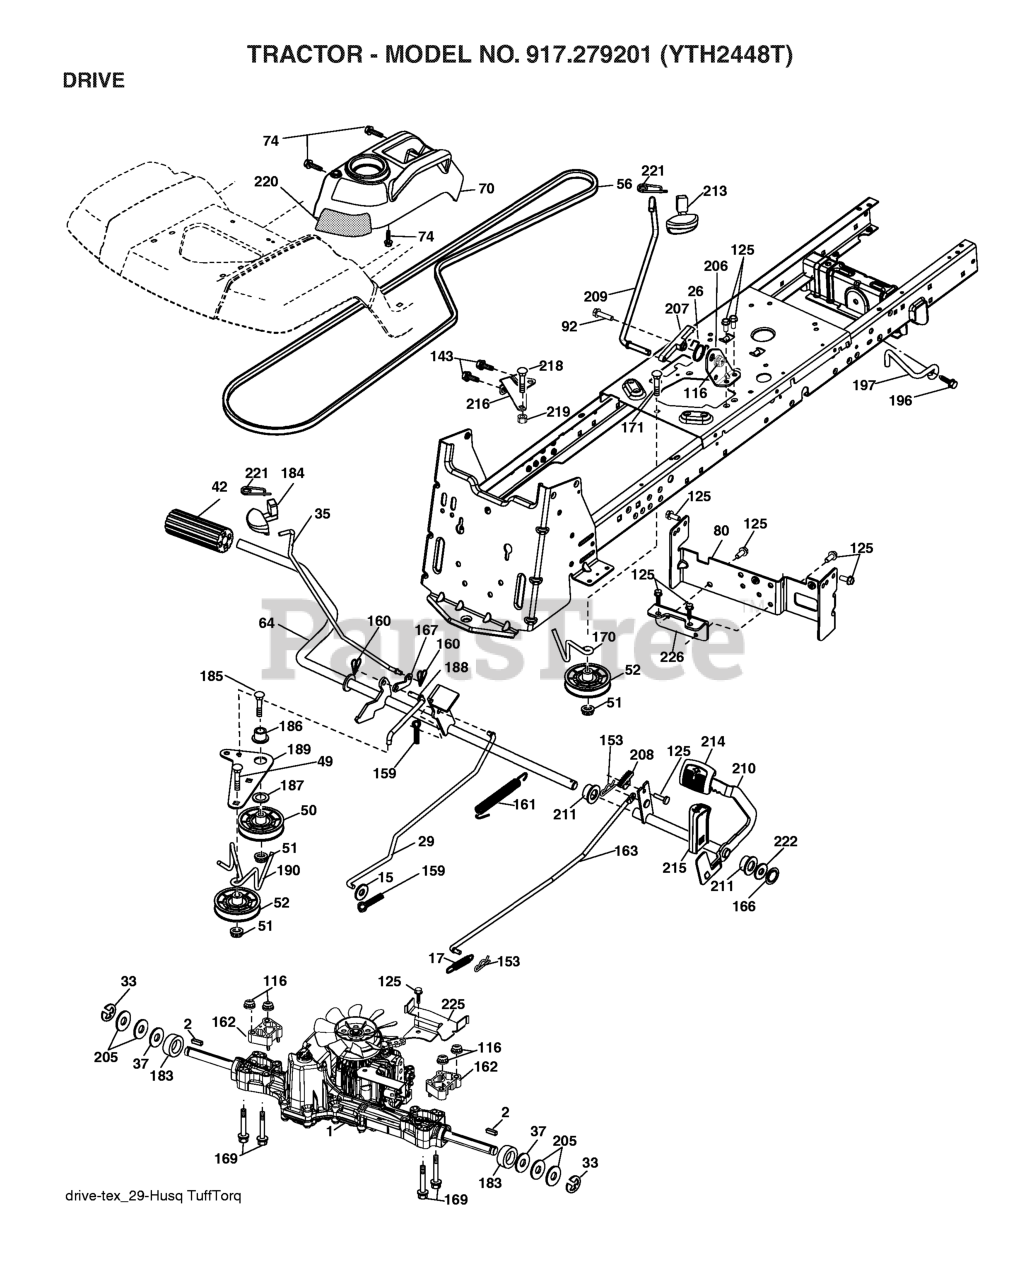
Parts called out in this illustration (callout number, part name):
1	TRANSAXLE.K46BN.PEDAL CONTROL
2	SQUARE KEY
15	WASHER
17	SPRING.BRAKE.K46
26	SPRING.RETURN.CRUISE
29	ROD.BRAKE.K46
35	ROD.BRAKE.PARKING.GT.H
42	PEDAL COVER T
50	IDLER.FLAT.910.OFFSET
51	NUT LOCK FLG 3/8-16 UNC
52	IDLER.V-GROOVE.910.OFFSET
56	V-BELT.MOWER.92.40.42/K46
64	SHAFT.ASM.PEDAL.BRK.CNTR
70	RP CONSOLE.ASM.PCH.W/TB
74	SCREW.HI-LO.CONSOLE
80	STRAP.TORQUE.HG3000/K46
92	BOLT
116	NUT LOCK HEX FLANGE 5/16-18
125	SCREW
143	Screw 5/16-18 x 1/2 Hex, Self Tapping 5/16-18 x 1/2
153	RETAINER M
159	COTTER PIN
160	RETAINER CLIP
161	SPRING.RETURN.CLUTCH.2006
162	SPACER.TRANSAXLE.18&22
163	ROD.CONTROL.PEDAL.K46
166	NUT.PUSH.625.2006
167	LATCH.BRAKE.SPRING
169	BOLT.HEX.FLNG.5/16-18X3.75
170	KEEPER.V-IDLER.CENTER.
183	SPACER AXLE
184	HANDLE.PARKG.BRK.HUSQ X667
186	SPACER.RETAINER
187	WASHER 12/32X2X10GA
188	RP.LINK.CLUTCH.GROUND.DRIVE
189	BELLCRANK.GROUND.DRIVE.TEX.
190	KEEPER.BELLCRANK.DRIVE
196	SCREW 3/8-16X1
197	LINK.CLUTCH.ANIT-ROTAT
206	BRKT.MOUNT.LATCH.CRUIS
207	LATCH.CONTROL.CRUISE
208	GEAR.SECTOR.CONTROL.CR
209	ROD.CONTROL.CRUISE.GT.
210	ROCKER.ASM.PEDAL.CONTR
211	BEARING.NYLON
213	KNOB.CONTROL.CRUSIE.HU
214	PEDAL.FORWARD.TEX.GT.4
215	PEDAL.REVERSE.TEX.GT.4
216	BRACKET.PULLEY.IDLER.W/TEX
218	BOLT.5/16-18X1-1/4 FULL.THREAD
219	SPACER.FENDER
220	REFLECTOR.RH.TEX GT
221	RETAINER.SPRING.CLIP.H
222	WASHER
225	KEEPER.BELT.TRANSAXLE.K46
226	BRKT.MOUNT.TORQUE.K46.
